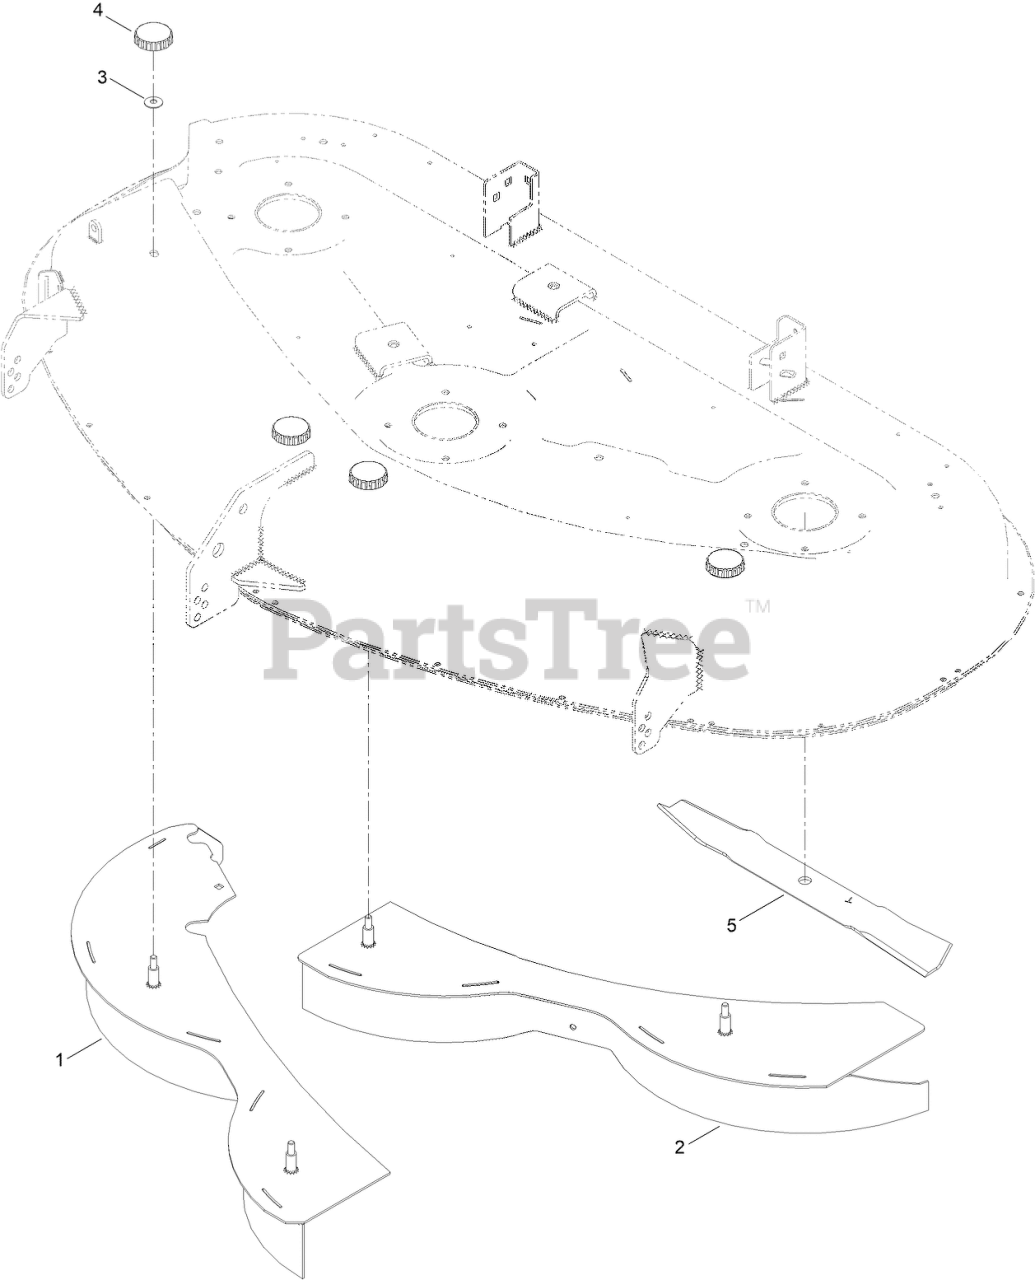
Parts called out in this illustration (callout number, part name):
1	RH BAFFLE ASM
2	LH BAFFLE ASM
3	WASHER-BELLEVILLE
5	BLADE-MULCH, 18.75 INCH
